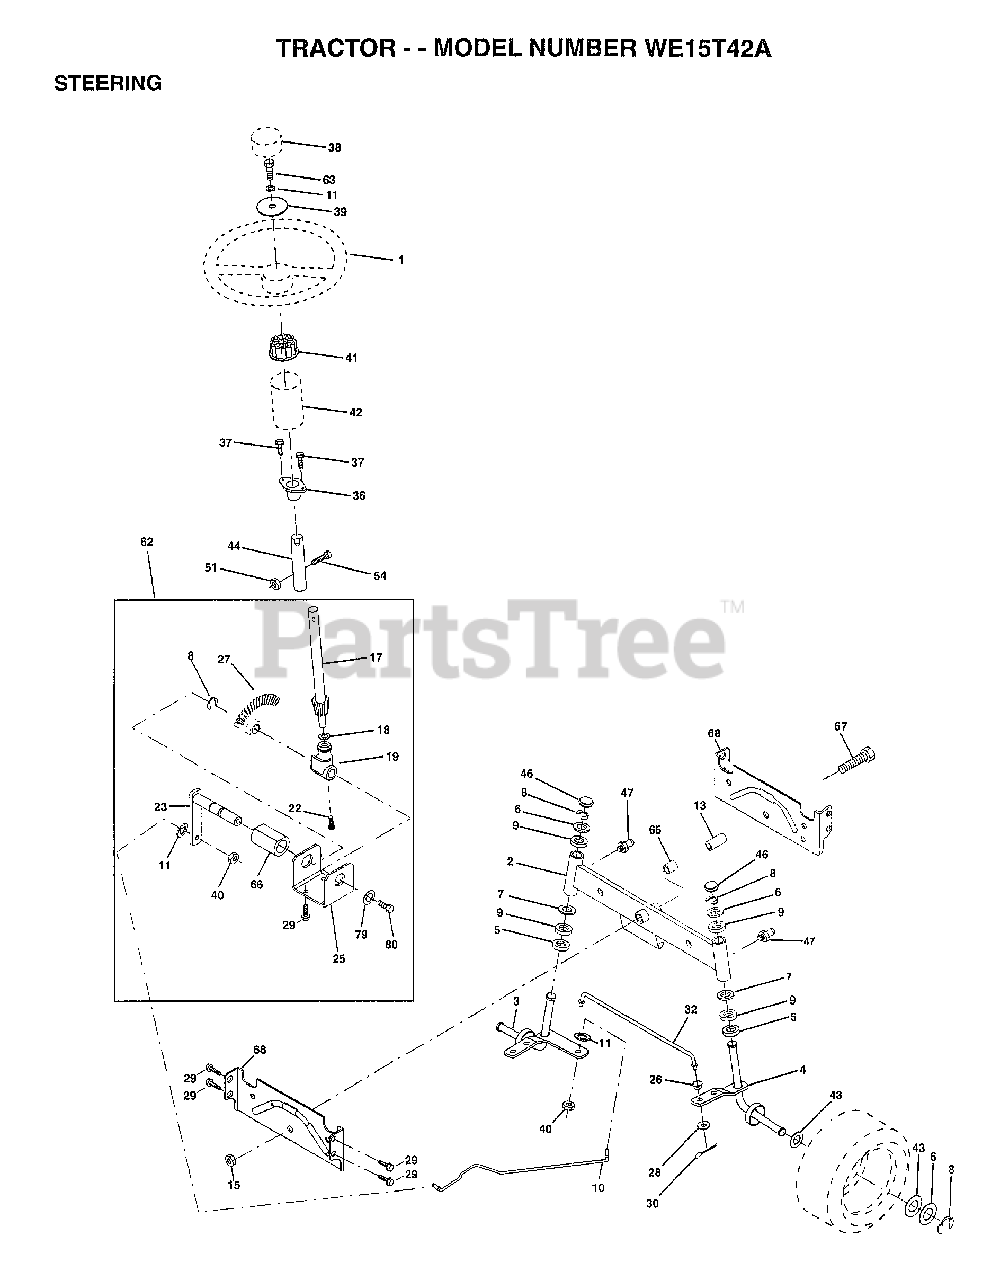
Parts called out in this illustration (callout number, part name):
1	WHEEL STR AYP BLK
2	AXLE ASM
3	SPINDLE.ASM.LH
4	"SPINDLE ASM,RH"
5	WASHER .T
6	WASHER
7	WASHER
8	RING
9	COL. SRTG. BEAR.
10	DRAGLINK-STAMPED
11	LOCKWASHER
13	BEARING AXLE
15	"NUT-LOC,FLANGE LT"
17	SHAFT ASM STEERIN
18	THRUST WASHER
19	SUPPORT.SHAFT.STEER
22	SCREW.HX.WSH.HD
23	SHAFT.ASM.PITMAN
25	BRKT-STEERING
26	BUSHING.DRAGLINK
27	GEAR SECTOR
28	WASHER
29	SCREW
30	COTTER PIN
32	TIE ROD
36	BUSHING.STEERING
37	"SCREW-TT,10-32 FL"
38	CAP STEER AYP
39	WASHER T
40	GRIPCO NUT
41	ADAPTER LT
42	BOOT.STEER.PL
43	WASHER
44	EXT SHAFT STEERIN
46	CAP
47	ZERK M
51	NUT
54	BOLT
62	KIT.STEER.ASM
63	BOLT
65	SPACER AXLE
66	"BEARING-ARM,PITMA"
67	BOLT
68	BRACE AXLE
79	WASHER
80	BOLT.HX.NYLON3/8-16X3/
